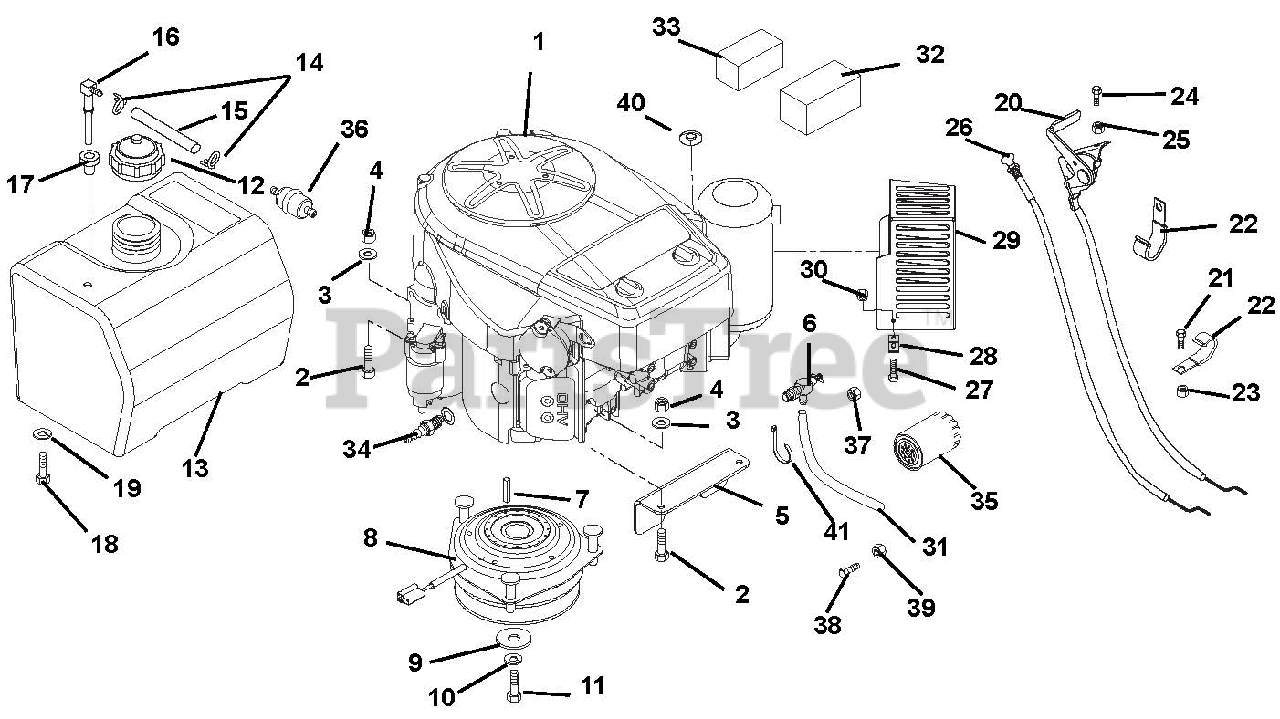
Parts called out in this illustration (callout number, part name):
1	Engine, 15 HP Kawasaki
1	Engine, 13 HP Kawasaki
2	Bolt-Hex .31-18 x 1.75 Grade 5
3	Washer-Locking .31 x .078 Regular
4	Nut-Hex .31-18
5	Bracket, Clutch
6	Valve, Oil Drain
7	Key-Square .25 x 1.25 x 25 SAE 8630 OR SAE 1035
8	Clutch, Electric
9	Washer-Flat-Steel .469 x 2.00 x .25
10	Washer-Locking .44 x .109 Regular
11	Bolt-Hex .44-20 x 3.00 Grade 5
12	Cap, Fuel
13	Tank, Fuel
14	Clamp-Hose Wire .49/.51 x .116
15	Gas Line-Bulk .25 I.D.
16	Fitting, Tank
18	Bolt-Hex .38-16 x .75 Grade 5
19	Washer-Locking .38 x .094 Regular
20	Cable, Throttle-with Liner
20	Cable- Throttle-with Liner
21	Bolt-Hex .31-18 x .75 Grade 5
23	Nut-Locking-Nylon .312-18
24	Screw-Machine 10-24 x .75 Hex Washer Head
25	Nut-Locking-Nylon 10-24 with Insert
26	Control, Choke
27	Bolt-Hex .31-18 x .75 Grade 5
28	Bracket, Muffler Guard
29	Guard, Muffler
30	Nut-Locking-Center .31-18
31	Tube, Oil Drain
32	Filter, Air Paper
33	Filter, Air Foam
34	Spark Plug
35	Filter, Oil
36	Fuel Filter- Kawasaki
37	Nut-Locking-Center .31-18
38	Bolt-Hex .38-16 x .75 Grade 5
39	Nut-Locking-Center .38-16
40	Washer-Flat-Steel .38 x .87 x .179
41	Cable Tie
